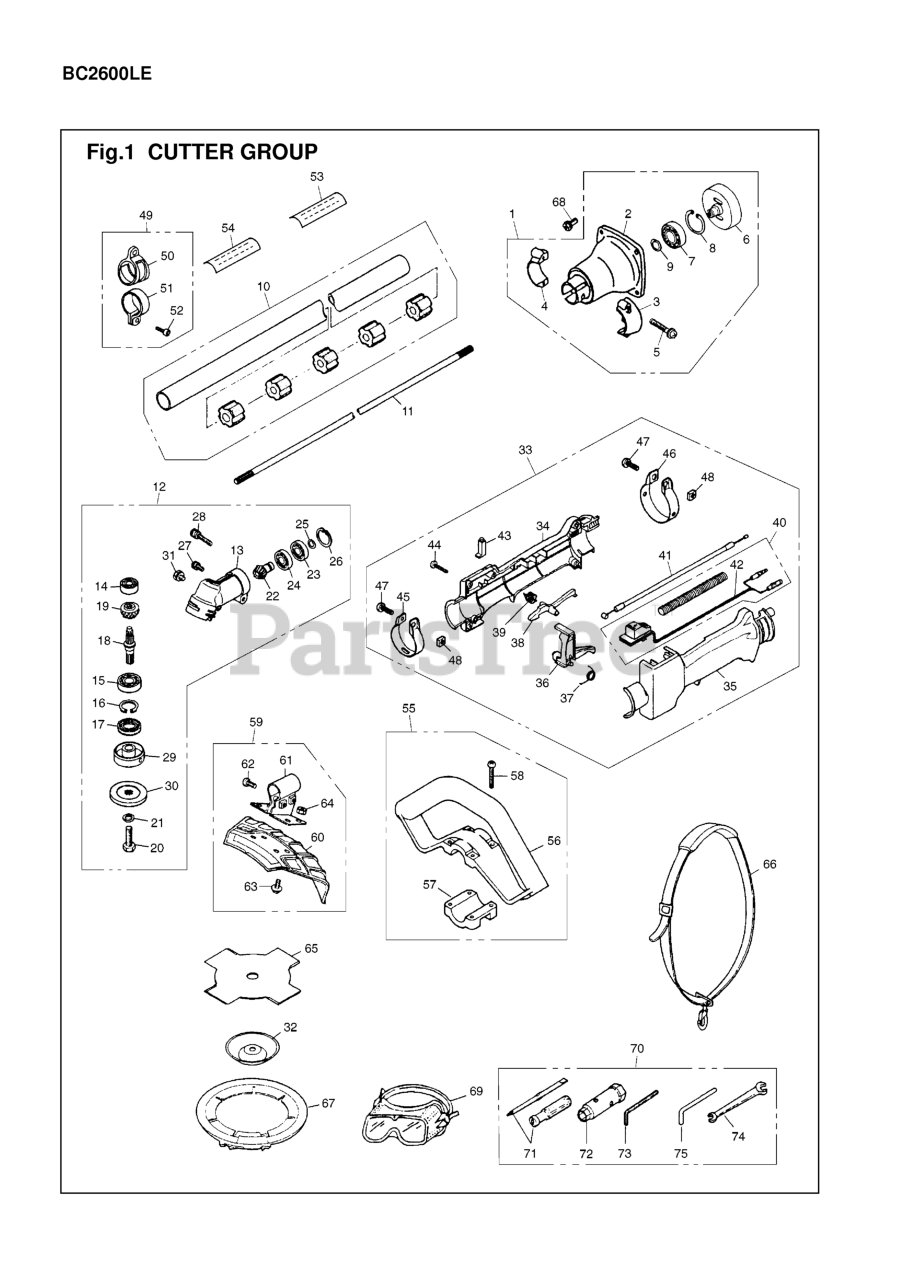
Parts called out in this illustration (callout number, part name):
1	HOUSING ASSY
3	CLAMP, LEFT
4	CLAMP, RIGHT
5	BOLT
7	BEARING
8	RING
9	RING
10	PIPE (USE -11302)
11	SHAFT, DRIVE
12	GEARCASE ASSY
13	GEARCASE
14	BEARING
15	BEARING
16	SNAP RING
17	SEAL
19	GEAR
20	BOLT
21	WASHER
23	BEARING
24	BEARING
25	SNAP RING
26	SNAP RING
27	BOLT
28	BOLT
29	HOLDER (A)
30	HOLDER (B)
32	COVER (RPLS 6460-13280)
33	GRIP ASSY
37	SPRING
39	SPRING
40	SWITCH COMP
41	CABLE COMP
42	CORD COMP
44	SCREW
46	BAND
48	NUT
49	HANGER ASSY
50	HANGER (REPLACES -18100)
53	PLATE NAME
54	PLATE, CAUTION
55	HANDLE ASSEMBLY
56	HANDLE
59	GUARD ASSY.
60	GUARD
66	STRAP ASSY
67	COVER (REPLACES D0041) ACC.
68	BOLT, M6 x 20
70	TOOL SET
71	DRIVER
74	SPANNER
75	BAR
